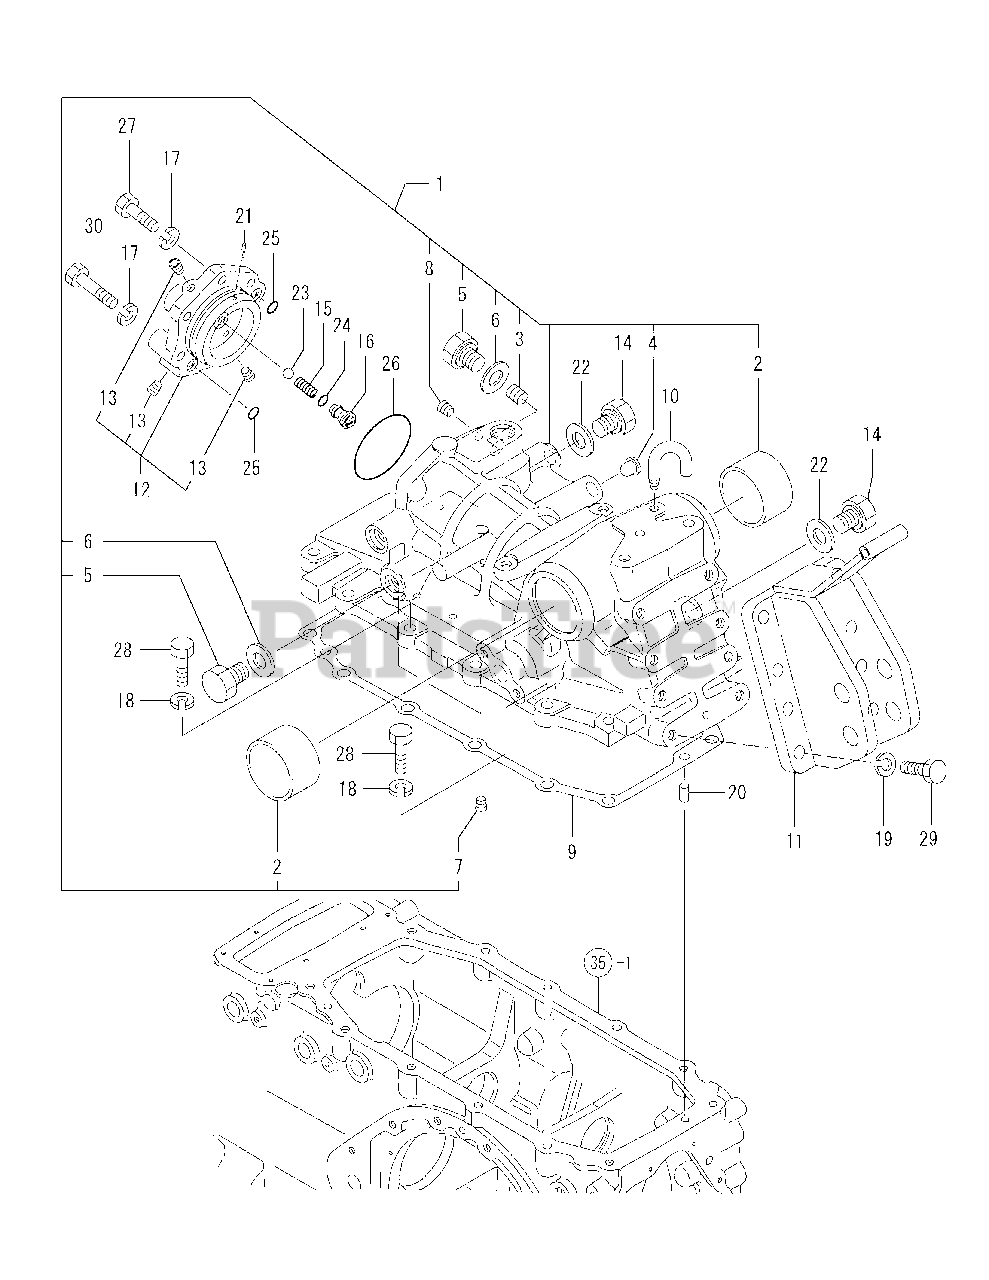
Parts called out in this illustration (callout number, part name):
1	HOUSING, HYDRAULIC
5	PLUG 3/4-16UNF
7	PLUG PT1/8,SCREW
8	PLUG PT1/4,SCREW
9	PACKING, HOUSING
10	BREATHER, AIR (23)
11	HINGE, TOP LINK
12	HEAD ASSY, CYLINDER
13	PLUG PT1/8,SCREW
14	PLUG 3/4-16UNF
17	SPRING WASHER 12
18	SPRING WASHER 12
19	SPRING WASHER 12
20	PARALLEL PIN 10X 18
21	SPRING PIN 4X16
24	O-RING 1B P-12.0
25	O-RING 1B P-14.0
26	O-RING 1B G-80.0
27	BOLT M12X 35 PLATED
28	BOLT M12X 35 PLATED
29	BOLT M12X 35 PLATED
30	BOLT M12X 55 PLATED
